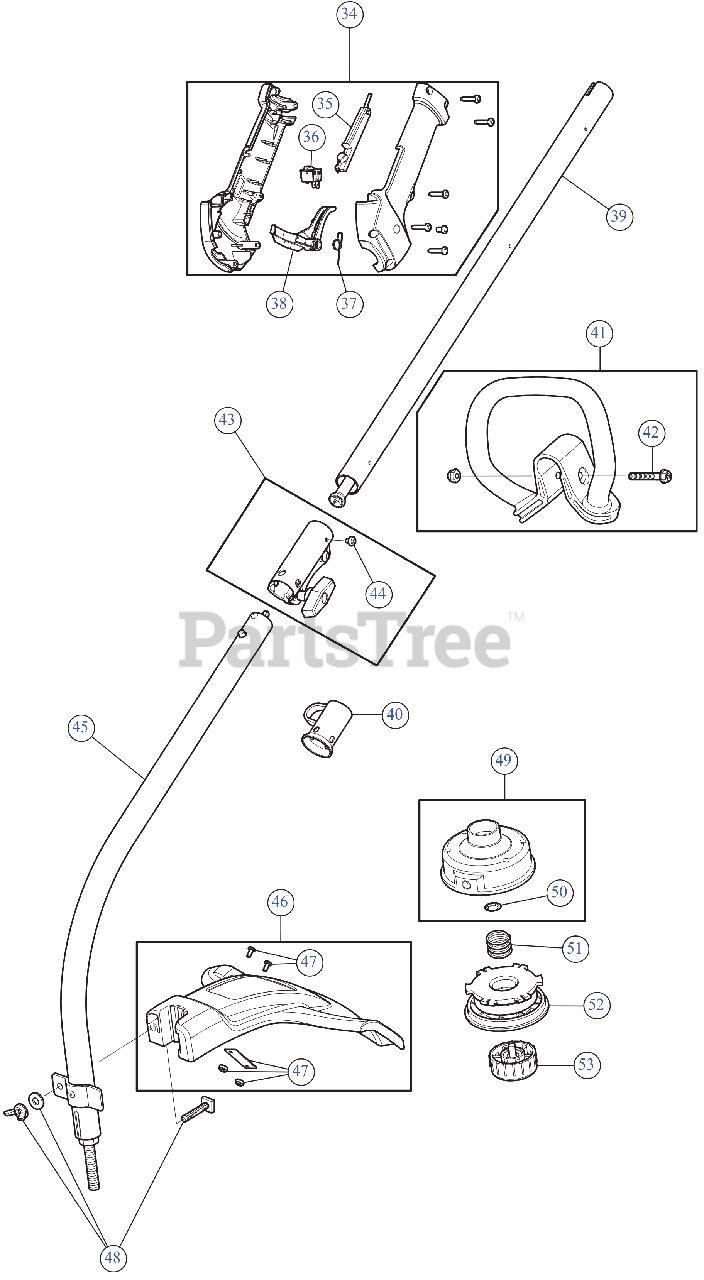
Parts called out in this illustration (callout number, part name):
34	THROTTLE GRIP ASSEMBLY
35	LEVER LOCK OUT
36	SW, MOMENTARY ON/O
37	SPRING TRIG
38	THROTTLE TRIGGER
39	BOOM ASSEMBLY UPR
40	HANGER
41	D-HANDLE
42	BOLT 1/4-20X1 1/2
43	COUPLER ASSEMBLY
44	SCREW, 10-32X.250 TA
45	BOOM ASSEMBLY W/FLEX DRIVE SHAFT
46	GUARD ASSEMBLY
47	ASSEMBLY, BLADE
48	BLADE GUARD MOUNTING HARDWARE
49	REEL:OTR W/RET
50	RETAINER .625 OD 2
51	SPRING-SPOOL
52	REEL-INNER SPOOL
53	BUMP KNOB (LIB RED)
